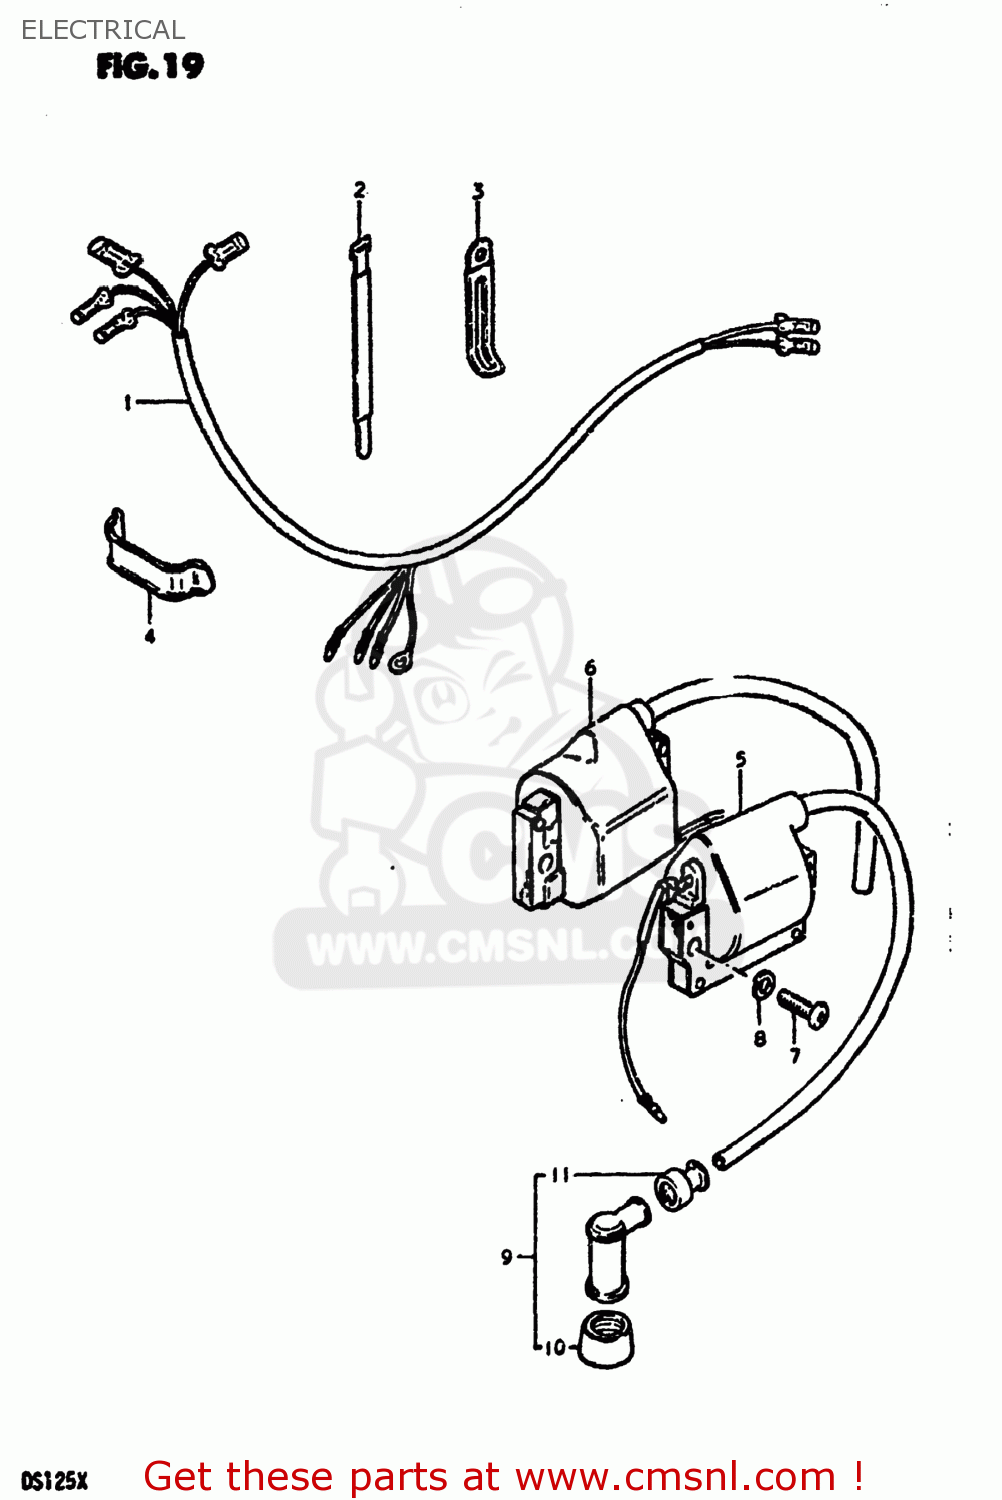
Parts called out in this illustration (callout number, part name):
1	HARNESS,WIRING
2	CLAMP
3	CLAMP
4	CLAMP
5	COIL ASSEMBLY,IGNITION
6	UNIT & COIL ASSEMBLY,IGNITION
7	SCREW
8	LOCK WASHER
9	CAP,SPARK PLUG
10	SEAL,SPARK PLUG
11	SEAL,SPARK PLU
